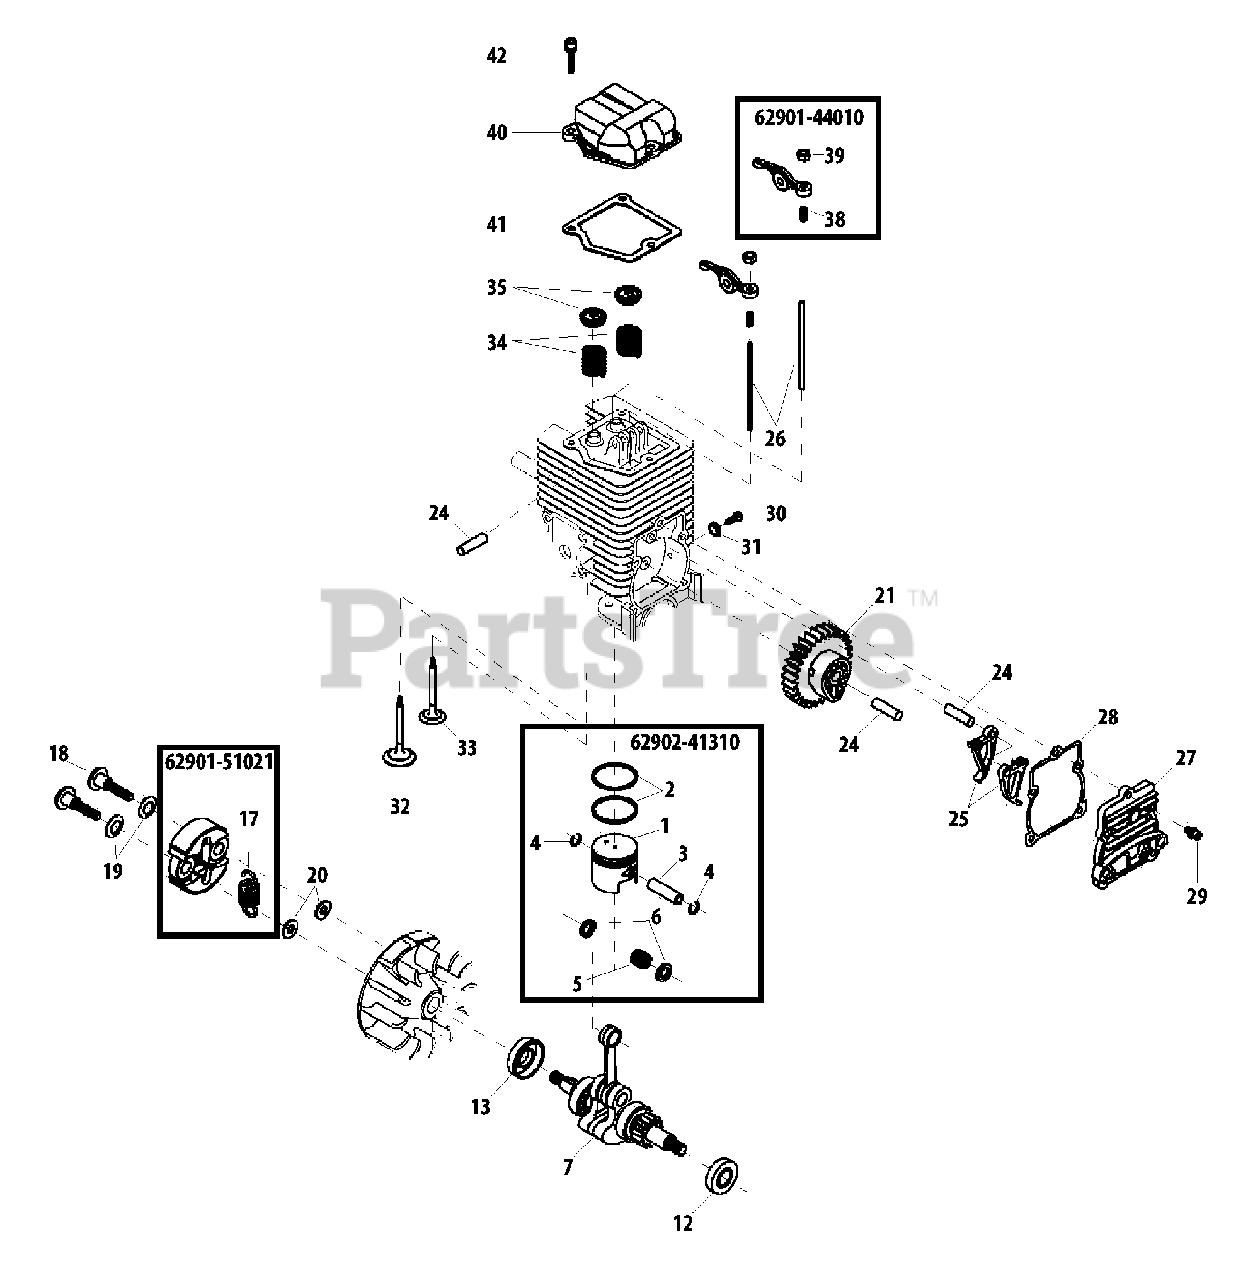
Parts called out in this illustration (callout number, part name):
1	PISTON
2	RING, PISTON
3	PIN, PISTON
4	RING, RETAINING
5	BEARING, NEEDLE
6	SPACER - 9
7	CRANKSHAFT ASSY
12	SEAL, OIL - 12
13	SEAL, OIL - 12
17	SPRING, CLUTCH
18	BOLT, CLUTCH
19	WASHER - SPRING
20	WASHER - 6
21	GEAR, CAM
24	PIN - LOCATING
25	FOLLOWER, CAM
26	PUSHROD
27	COVER, CAM GEAR
28	GASKET
29	SCREW - 4X14
30	SCREW - 5
31	WASHER
32	VALVE, INTAKE
33	VALVE, EXHAUST
34	SPRING, VALVE
35	VALVE RETAINER ASSY
38	SCREW, ADJUST
39	LOCKNUT, ADJUSTER
40	COVER, ROCKER ARM
41	GASKET
42	SCREW - 4X12
62901-44010	ROCKER ARM ASSY
62901-51021	CLUTCH ASSY
62902-41310	PISTON KIT
